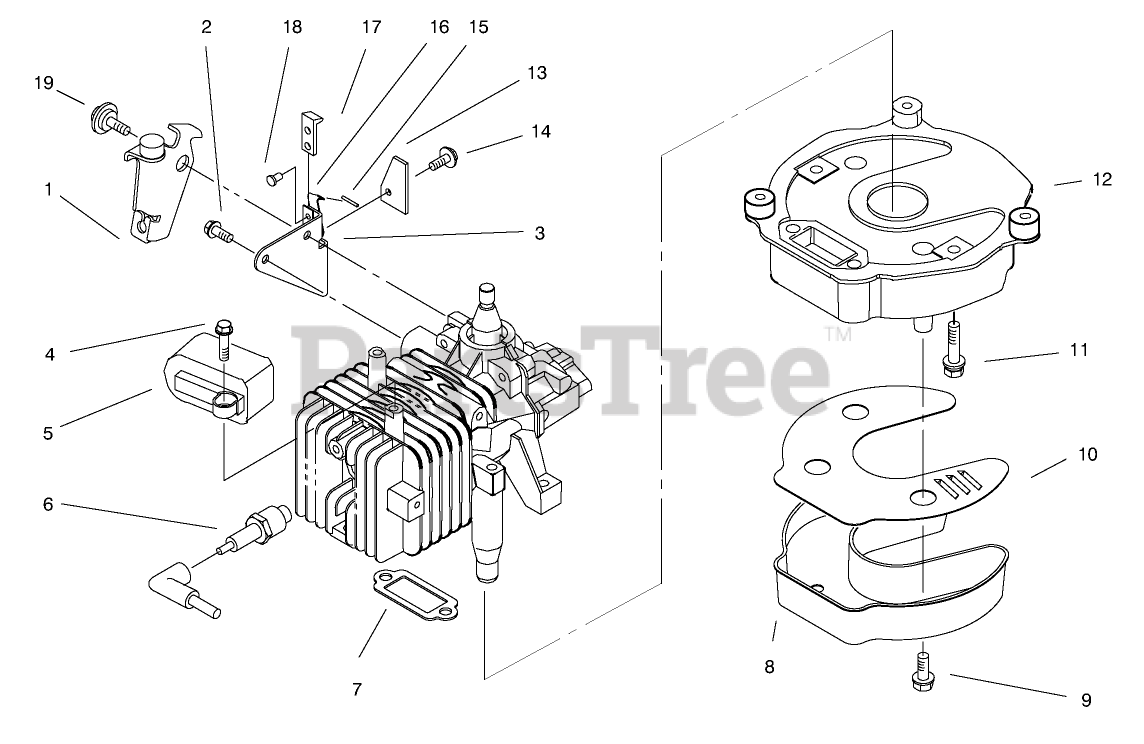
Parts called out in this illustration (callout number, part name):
1	PLATE-BRAKE
3	PLATE-BRAKE
4	SCREW
6	SPARK PLUG
7	GASKET-EXH. VF
9	SCREW
10	BAFFLE-MUFFLER
11	SCREW V
12	PLATE-MUFFLER V
13	STOP-GROUND STRAP
14	SCREW
15	ELECTRICAL LEAD ASM
16	STRAP-GROUND
17	STRAP-INSULATION
18	RIVET-PLASTIC
19	SCREW-SHOULDER
